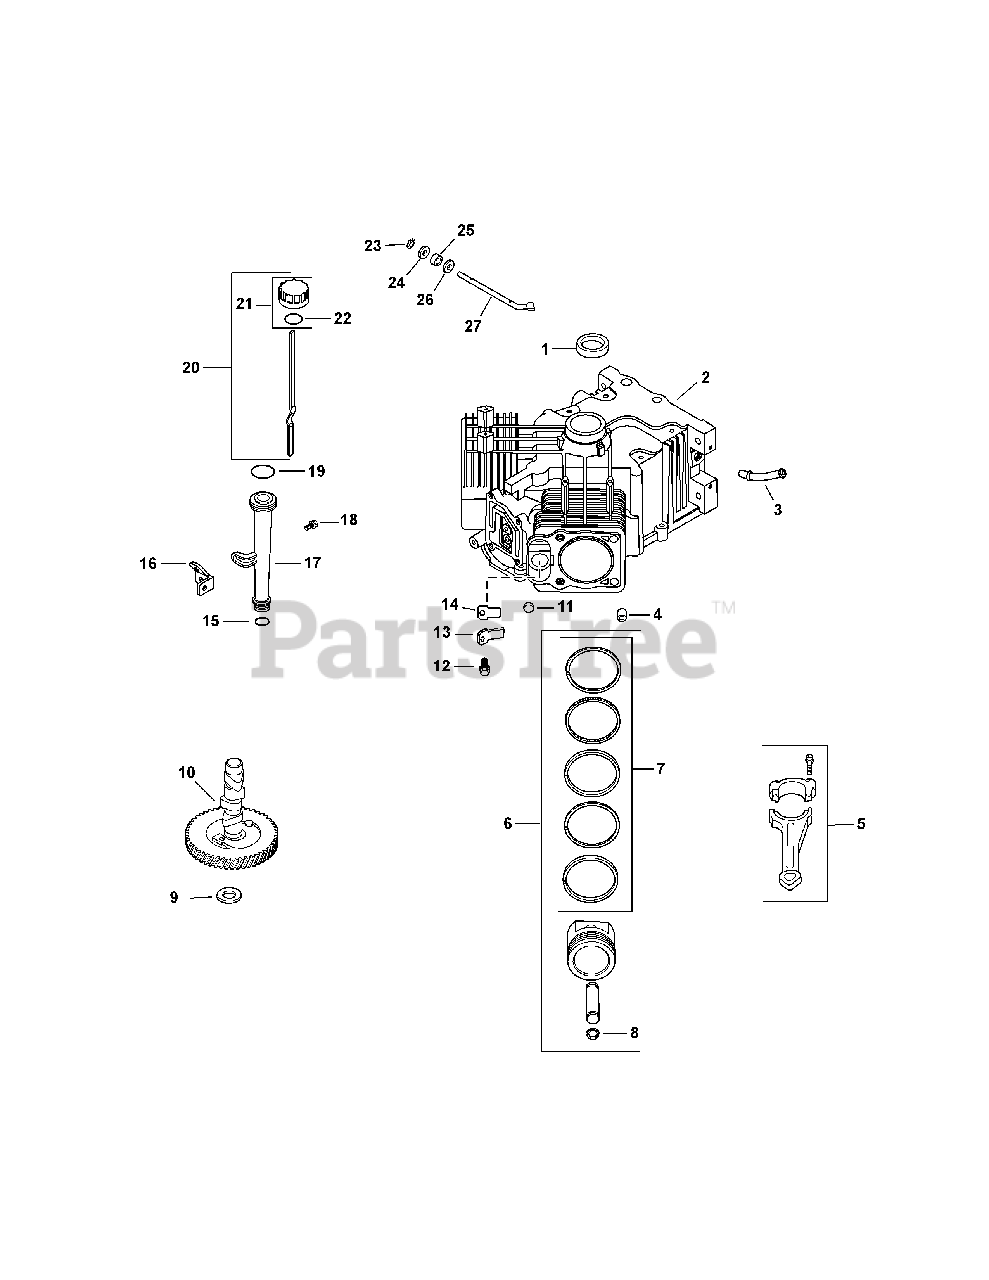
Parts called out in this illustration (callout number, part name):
1	SEAL, OIL (HELIX LIP)
2	CRANKCASE
4	PIN, LOCATING
5	ROD, ASSEMBLY CONNECTING (STD)
5	ROD, ASSY CONNECTING (.25 O.S.)
6	KIT,PISTON W/RNG SET (STD) 83mm (includes 7, 8)
6	KIT,PISTON W/RING (0.08) 83mm
6	KIT,PISTON W/RING (0.25) 83mm
6	KIT,PISTON W/RING (0.50) 83mm
7	RING SET (STD)
7	RING SET (.08)
7	RING SET (.25)
7	RING SET (.50)
8	RETAINER, PISTON PIN
9	SHIM, CAMSHAFT (WHITE .028'')
10	KIT, CAMSHAFT
12	SCREW, FLG THD FRM M5X.8X10
13	RETAINER, BREATHER REED
14	REED, BREATHER
15	O-RING, LOWER OIL FILL TUBE
16	BRACKET, OIL FILL TUBE
17	TUBE ASSEMBLY
18	SCREW, FLG THD FRM M5X0.8X16
19	O-RING, UPPER OIL FILL TUBE
20	DIPSTICK, ASSY (includes 21, 22)
21	KIT, OIL FILL CAP (YELLOW) (Includes 22)
22	O-RING, DIPSTICK
23	RETAINER, RING
24	WASHER, FLAT 9 MM
25	SEAL, GOVERNOR CROSS SHAFT
26	WASHER, FLAT 11/32''
27	SHAFT, GOVERNOR CROSS
